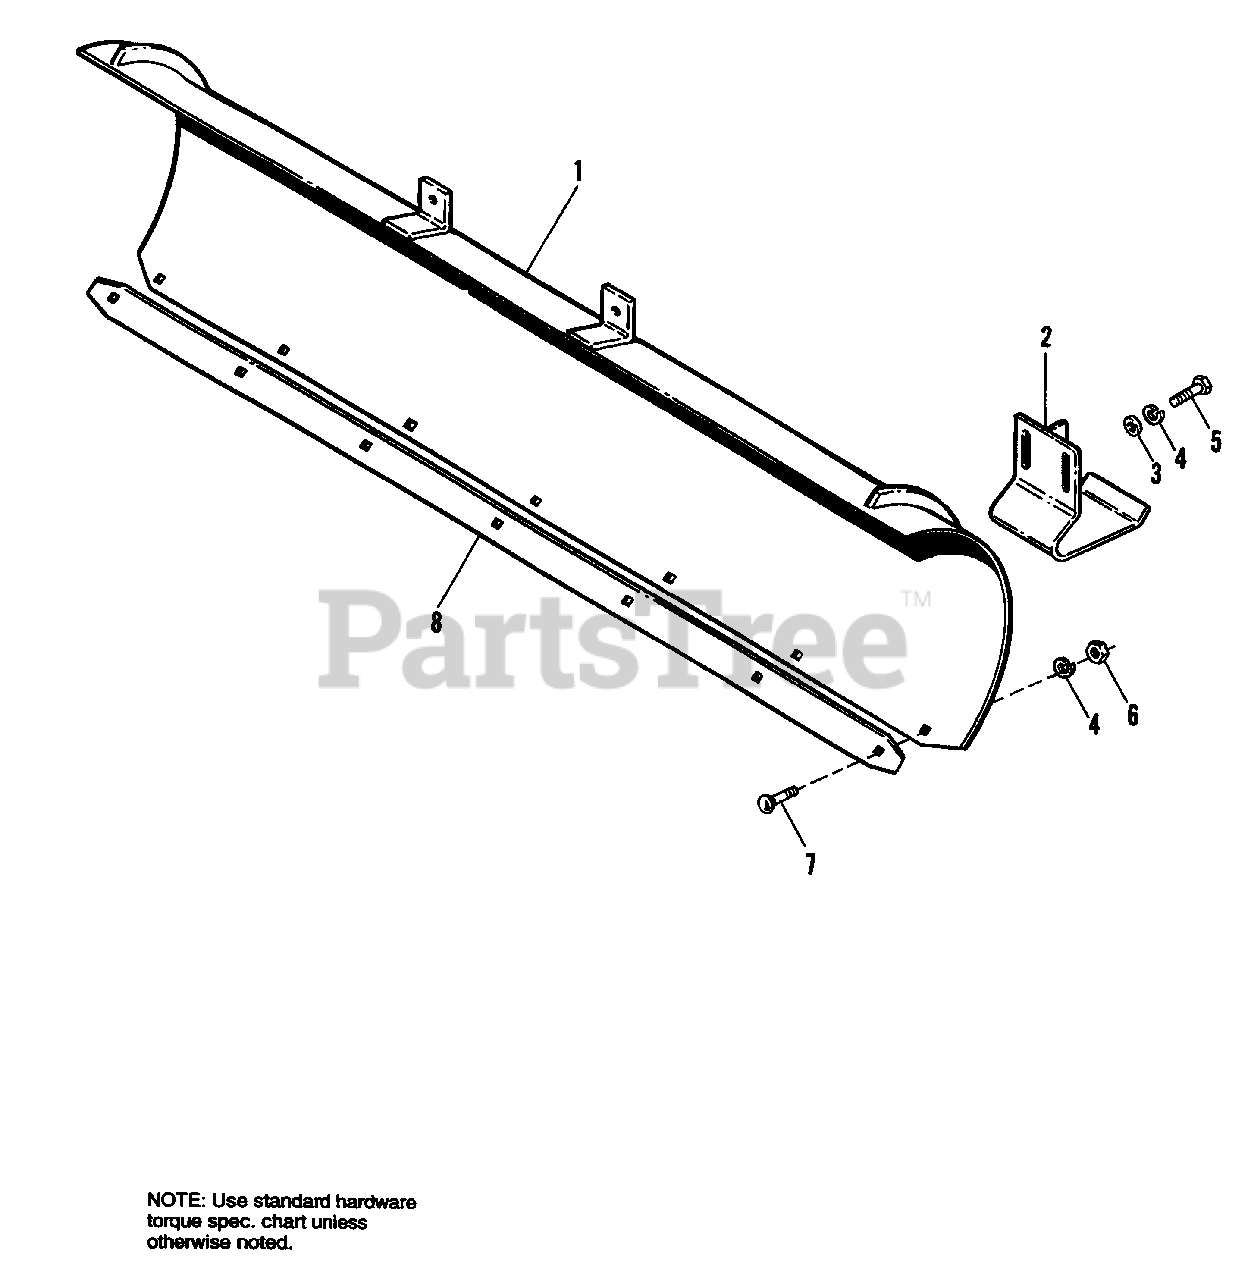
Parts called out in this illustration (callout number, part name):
1	BLADE ASSY.
2	SHOE ASSY.
3	WASHER, 3/8 Std.
4	LOCKWASHER, 3/8 Std.
5	CAPSCREW, Hex Hd., 3/8-16 x 3/4
6	NUT, Hex, 3/8-16
7	BOLT, Carriage, 3/8-16 x 1
8	PLATE, Wear
